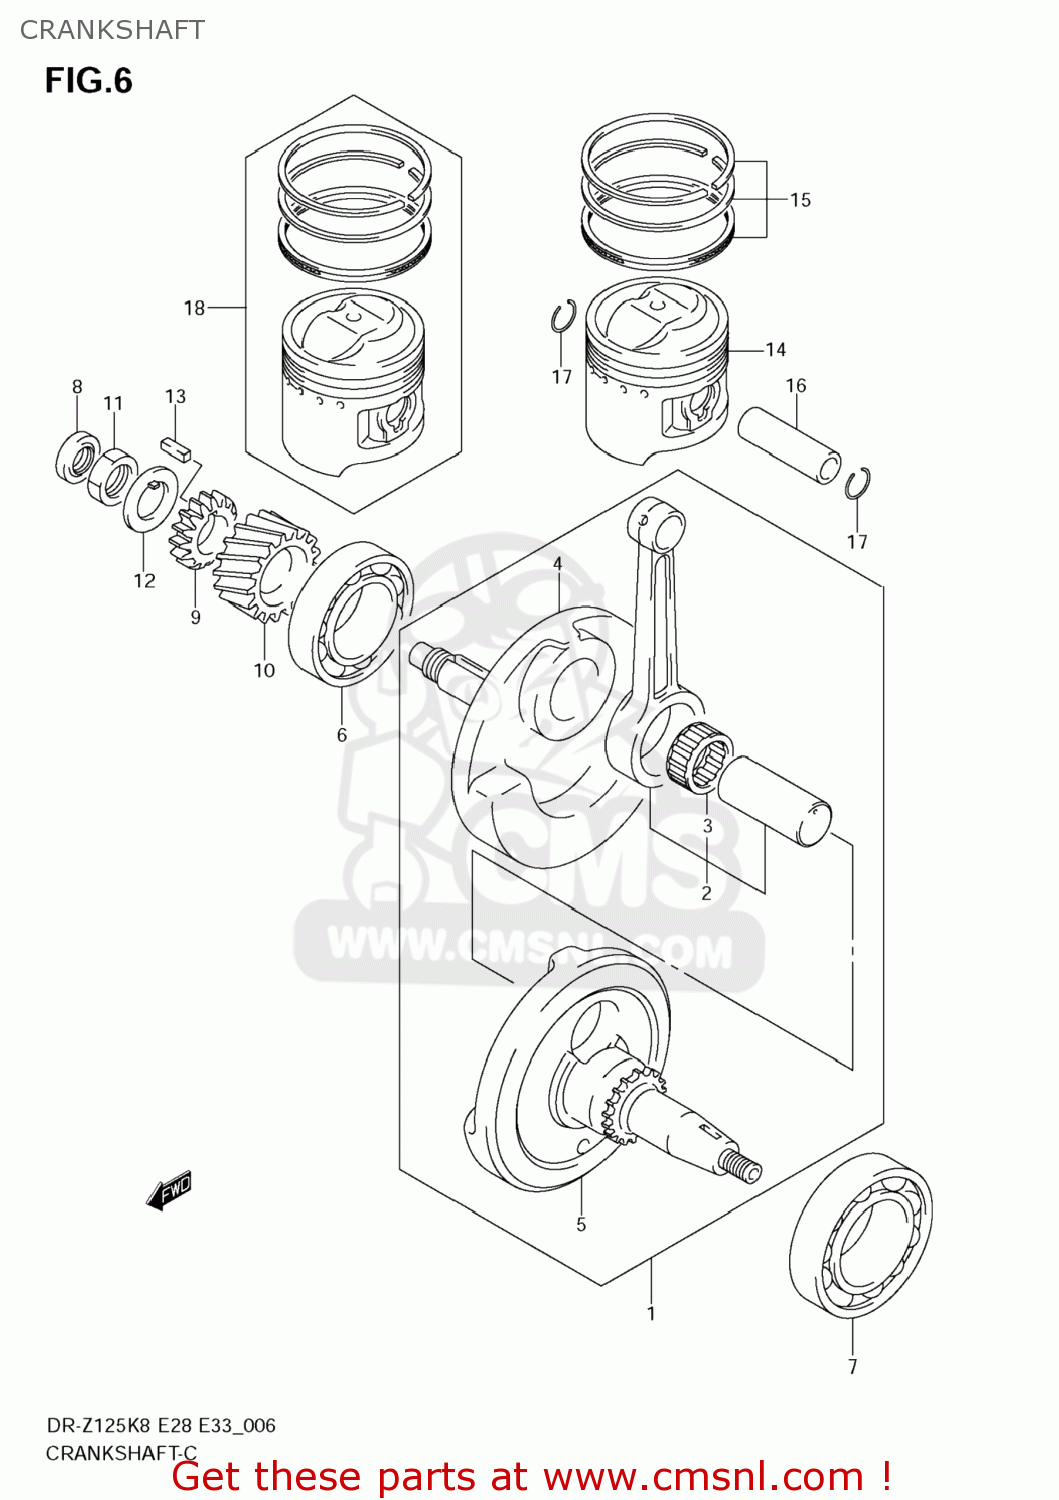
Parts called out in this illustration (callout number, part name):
1	CRANKSHAFT ASSY
2	CONNECTING ROD SET
3	BEARING(28X36X15.8)
4	CRANKSHAFT,R
5	CRANKSHAFT,L
6	BEARING(28X68X18)
7	BEARING(35X72X17)
8	SEAL,OIL(12X21X7)
9	GEAR,OIL PUMP DRIVE
10	GEAR,PRIMARY DRIVE(NT:17)
11	NUT
12	WASHER
13	KEY
14	PISTON
15	RING SET,PISTON
16	PIN,PISTON
17	RING,SNAP 14MM
18	PISTON SET(OS:0.5)
